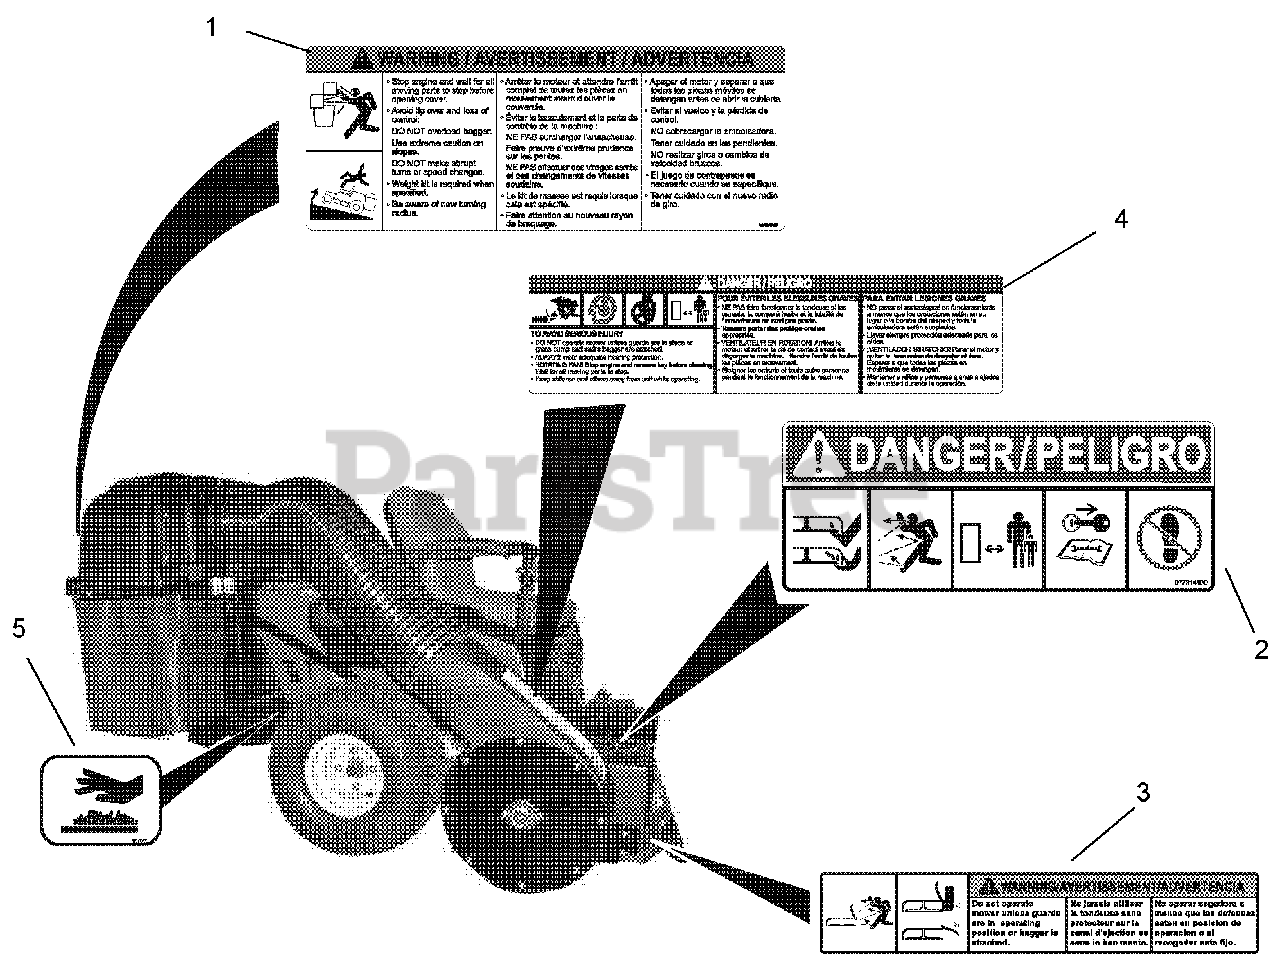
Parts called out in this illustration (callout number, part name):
1	Bagger Cover Decal
2	Mower Pan Danger Decal
3	Warning Decal
4	Grass Pump Caution Decal
5	Decal, Hot Surface
